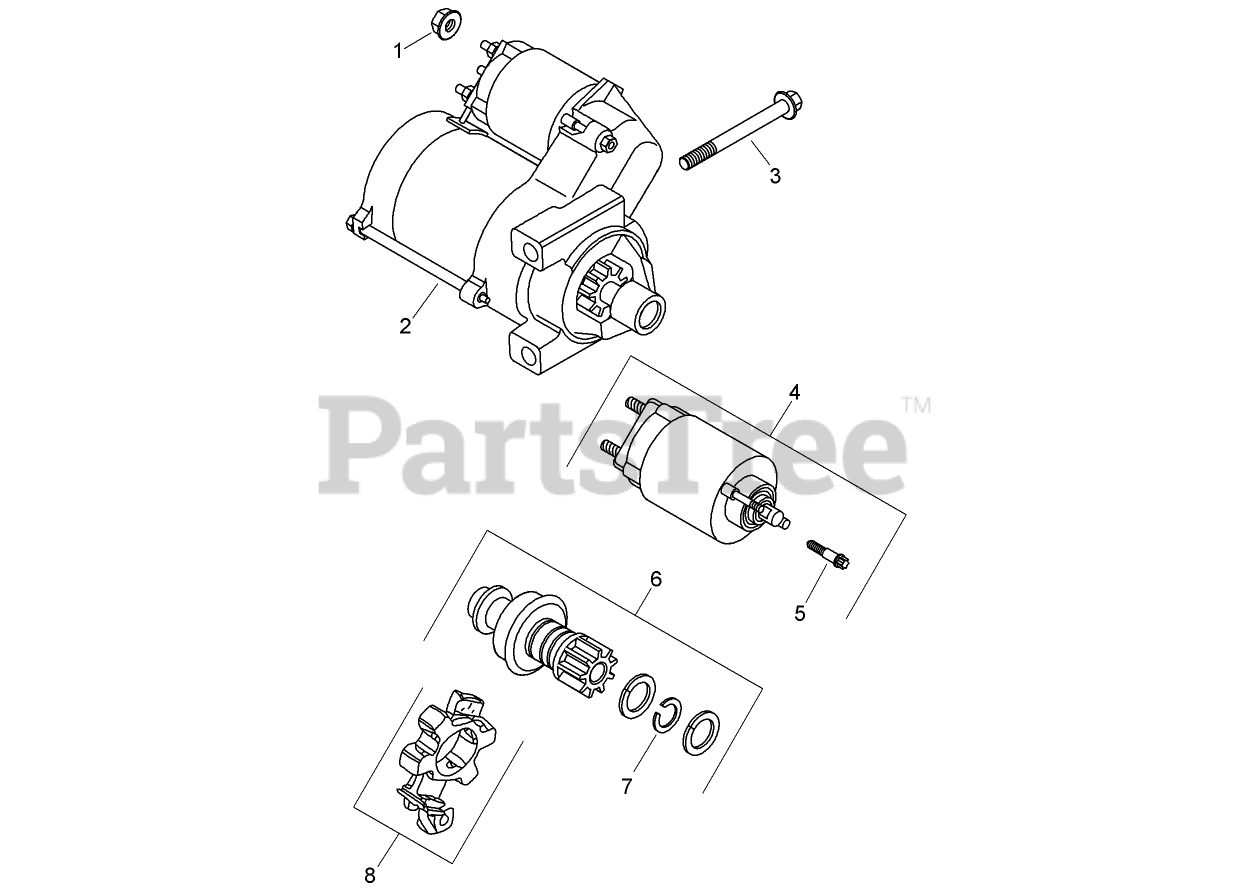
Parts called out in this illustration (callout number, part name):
1	NUT-FLANGE (M8X1.25)
2	STARTER ASM (SOLENOID SHIFT)
3	SCREW-FLG (M8X1.25X80)
4	Solenoid Kit (INCLUDES 5)
5	SCREW-TORX HEAD, EXTERNAL
6	Pinion Drive Kit (INCLUDES 7)
7	RING-RETAINING
8	BRUSH HOLDER KIT
